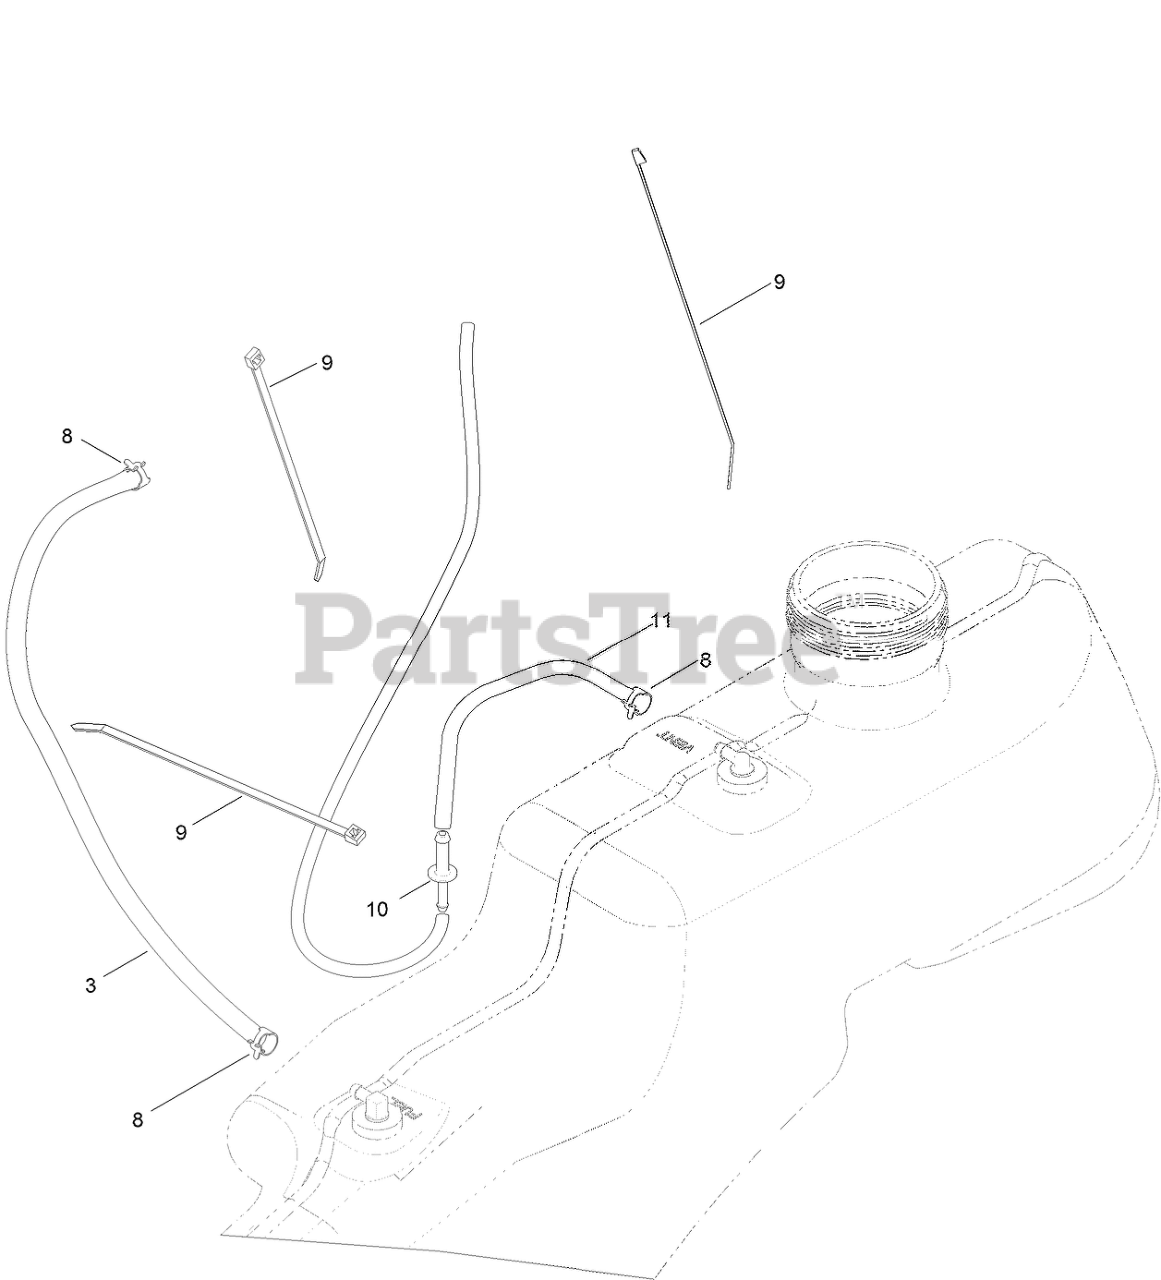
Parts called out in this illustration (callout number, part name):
3	HOSE-FUEL
8	CLAMP-HOSE
9	TIE-CABLE
10	ADAPTOR-ORIFICE
11	HOSE-FUEL
